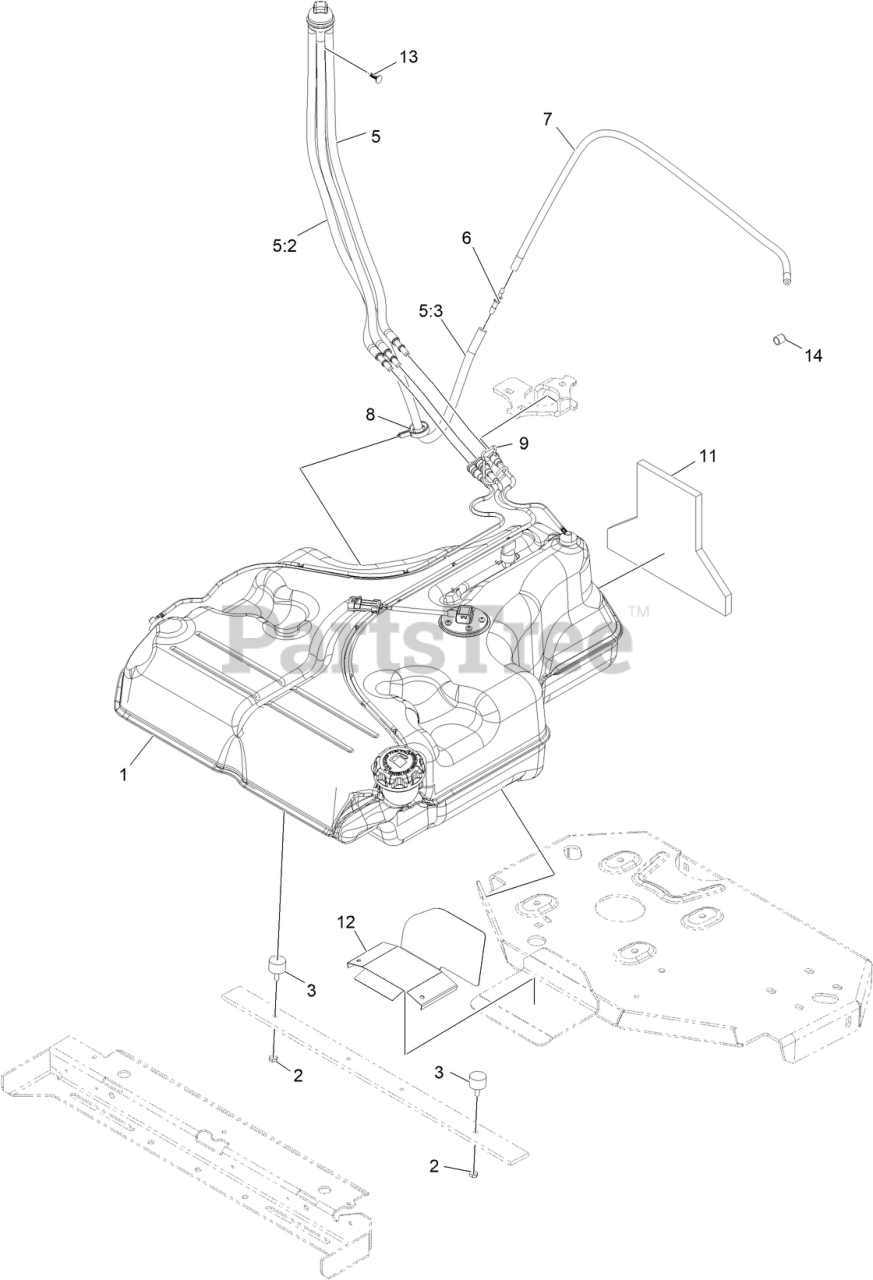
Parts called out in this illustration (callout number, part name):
1	FUEL TANK ASM
2	NUT-JAM
5	FUEL MANIFOLD VENT ASM
5:2	HOSE-FUEL
5:3	HOSE-FUEL
6	BARB-FUEL
7	HOSE-FUEL
8	CLAMP-HOSE
9	RETAINER-LINE, VAPOR
11	INSULATION-FOAM, FUEL TANK
12	GUARD-EXHAUST
13	PLUG-PLASTIC
14	PLUG-PORT
